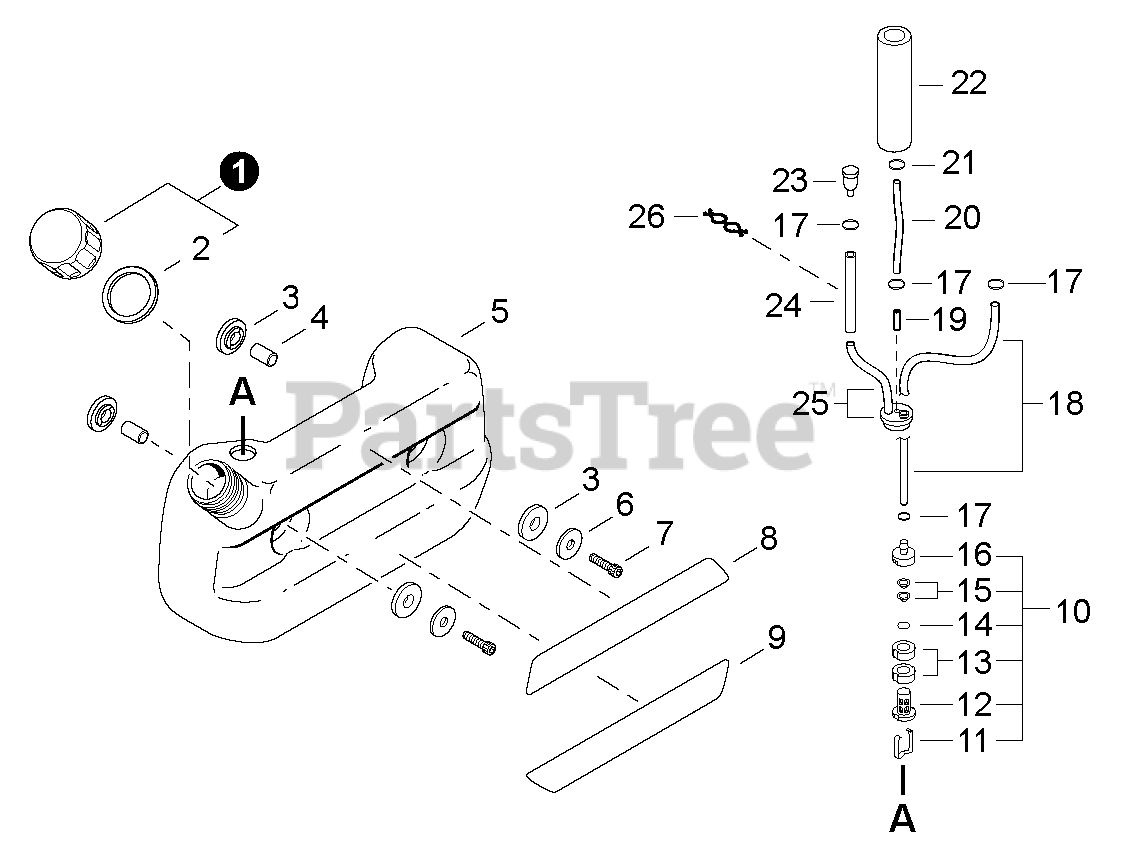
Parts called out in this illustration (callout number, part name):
1	CAP ASSY
2	GASKET, CAP
3	CUSHION
4	COLLAR
5	TANK, FUEL
6	COLLAR
7	SCREW - 6X25
8	LABEL - MODEL
9	LABEL - SHINDAIWA
10	FILTER, FUEL
11	FILTER, FUEL
12	FILTER, FUEL
13	FILTER, FUEL
14	RING, RETAINING
15	FILTER, FUEL
16	FILTER, FUEL
17	CLIP - 6
18	PIPE - FUEL
19	CONNECTOR, PIPE
20	PIPE - RETURN
21	CLIP
22	SLEEVE, INSULATOR
23	VENT, FUEL TANK
24	SLEEVE, INSULATOR
25	PIPE ASSY
26	CLIP
